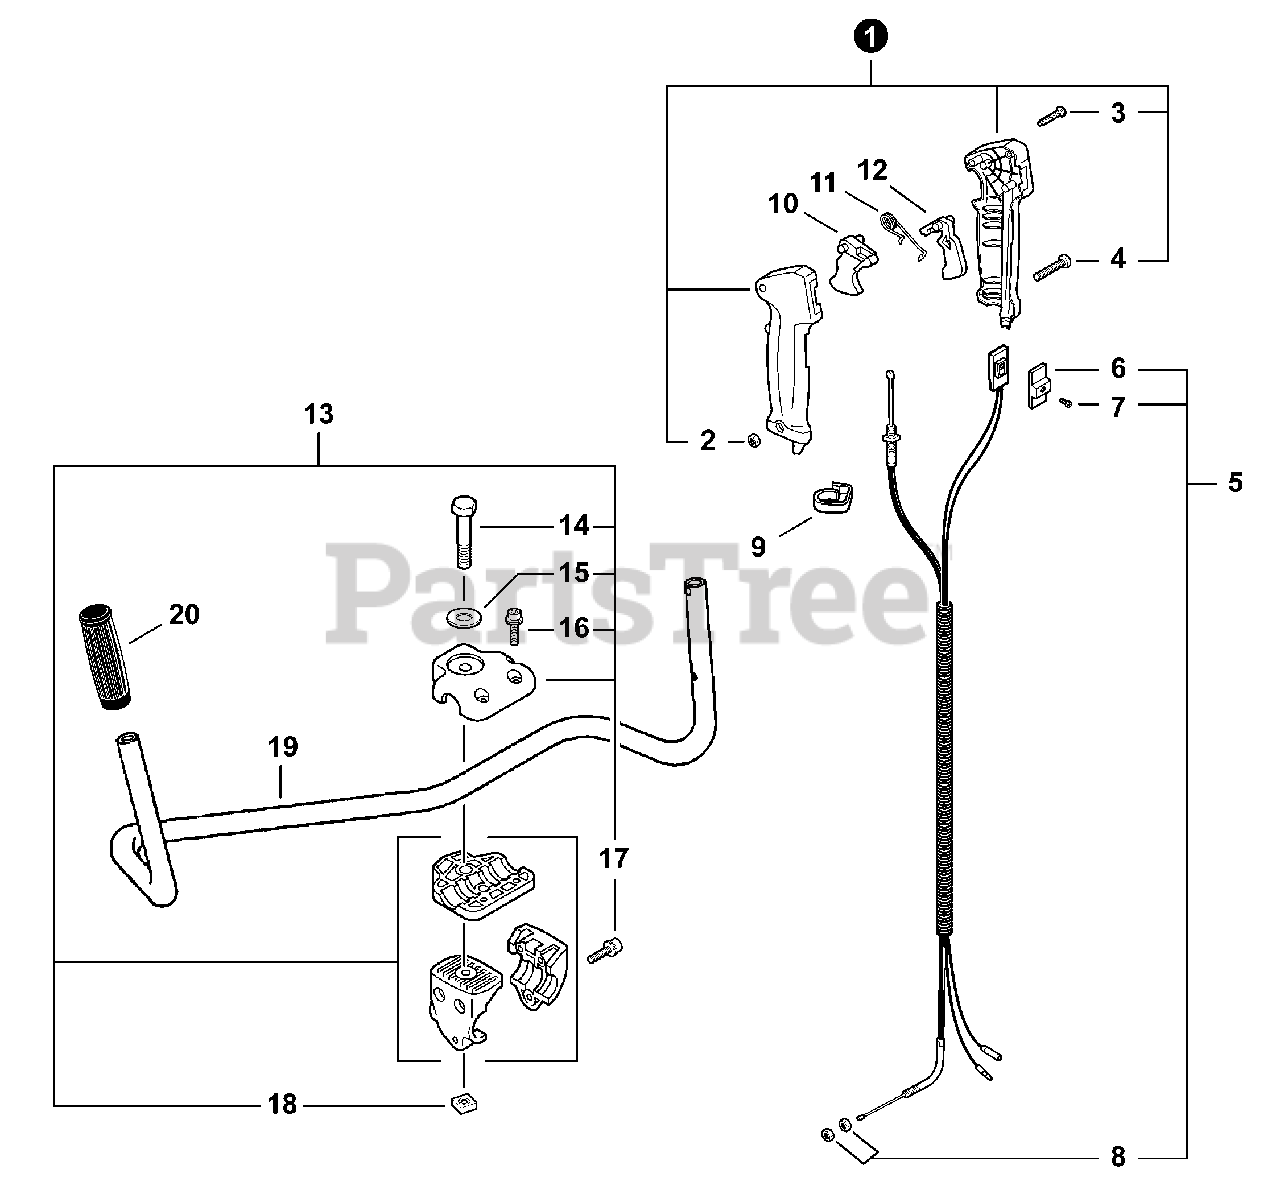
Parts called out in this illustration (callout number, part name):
1	CONTROL HANDLE KIT
2	NUT M5
3	SCREW 3×25
4	SCREW 5×30
5	CONTROL CABLE ASSY
6	KNOB, SWITCH - ORANGE
7	SCREW 3×10
10	TRIGGER, THROTTLE
11	SPRING, TORSION
12	LOCKOUT, THROTTLE
13	BRACKET KIT, HANDLEBAR
14	BOLT 8×55
15	WASHER 8
16	BOLT 5×20
17	BOLT 5×30
18	NUT 8×1.25
19	HANDLEBAR
20	GRIP, HANDLE
